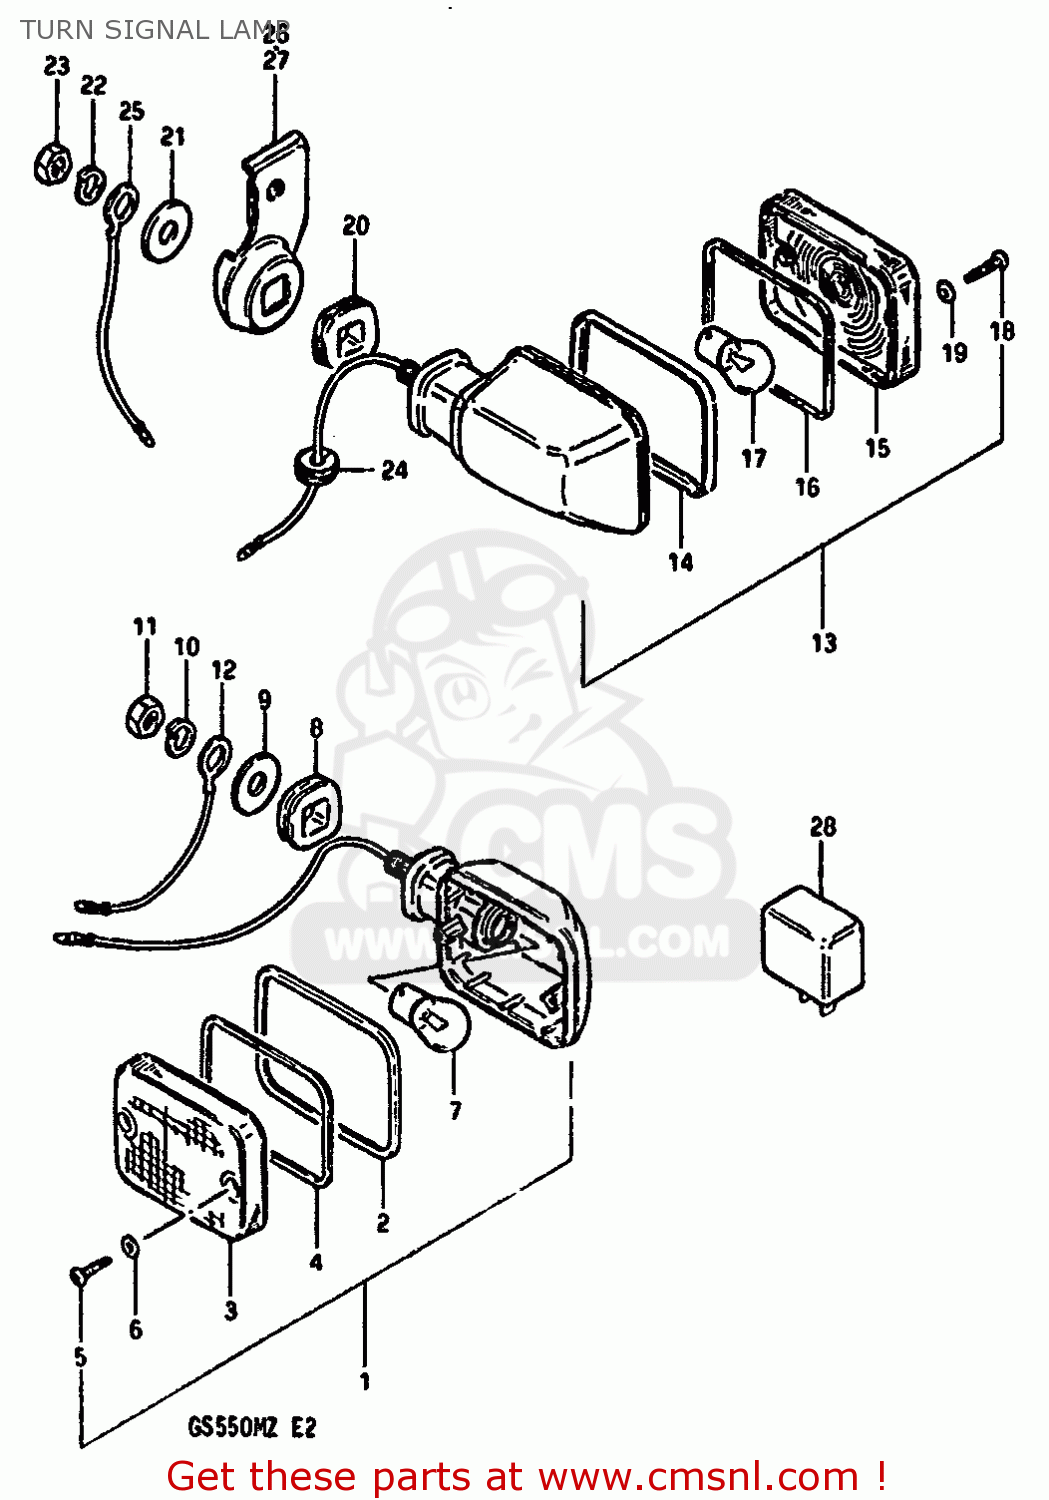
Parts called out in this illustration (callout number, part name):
1	LAMP ASSY,FR T
2	RIM
3	LENS
4	GASKET (NAS)
5	SCREW
6	GASKET (NAS)
7	BULB(12V21W)
8	CUSHION
9	WASHER (10.5X30X2.3)
10	LOCK WASHER
11	NUT
12	WIRE
13	LAMP, REAR TURN SIGNAL
14	RIM
15	LENS
16	GASKET (NAS)
17	BULB(12V21W)
18	SCREW
19	GASKET (NAS)
20	CUSHION
21	WASHER (10.5X30X2.3)
22	LOCK WASHER
23	NUT
24	GROMMET
25	WIRE
26	BRACKET,REAR TURN SIGNAL
27	BRACKET,REAR TURN SIGNAL
28	RELAY,TURN SIGNAL
